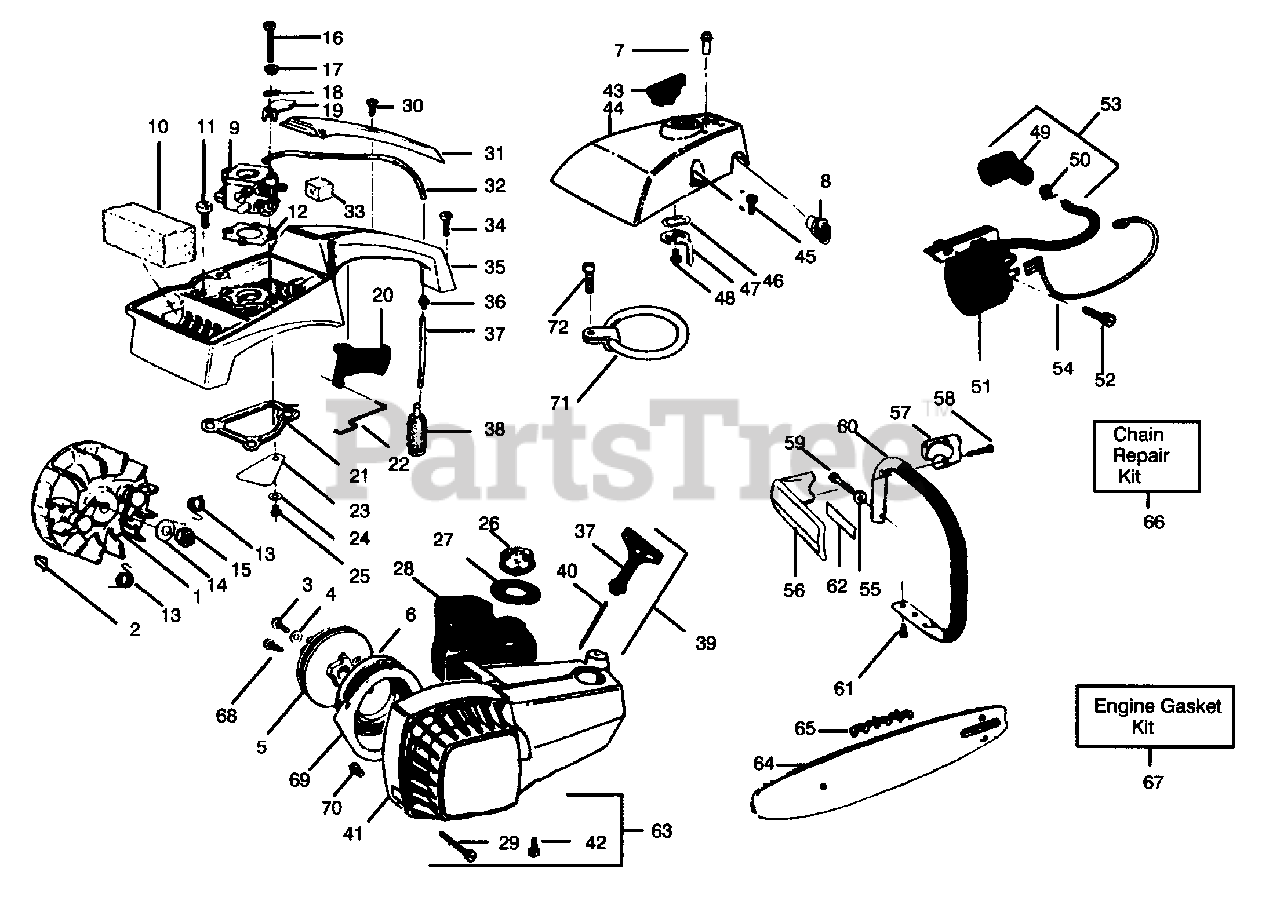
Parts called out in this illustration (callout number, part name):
1	Flywheel Ass'y.
2	Flywheel Key
3	Pulley Retaining Screw
5	Starter Pulley
6	Starter Spring
7	Grommet-Idle-190 only
8	Grommet-Mixture-190 only
9	Carburetor Kit w/Limiter Caps
10	Air Filter
12	Carburetor Gasket
13	Starter Dog Spring
14	Flywheel Washer
18	Wave Washer
19	Choke Shutter
20	Throttle Trigger
21	Gasket
22	Throttle Wire
23	Reed Valve, 190
23	Reed Valve, 180
24	Washer, 190
24	Washer, 180
26	Fuel Cap Ass'y.
28	Fuel Tank Ass'y. (Incl 26, 27 & 38)
29	Screw
31	Handle Cover
32	Line Kit
33	Throttle Wire Boot
35	Handle & Carb. Hsg., 180
35	Handle & Carb. Hsg., 190
36	Fuel Line Fitting
37	Starter Handle-180
38	Fuel Pick-up Ass'y.
39	Ass'y Rope & Handle
40	Rope Kit
41	Fan Hsg. Kit
43	Choke Knob
44	Carb. Cover, 180
44	Carb. Cover, 190
46	Wave Washer
47	Choke Lever
49	Spark Plug Boot
50	Spark Plug Connector
51	Ignition Module Kit
53	Spark Plug Lead
54	Switch Lead
56	Handguard-180
57	Handguard Cap-180
58	Screw-180
60	Handlebar
62	Handguard Decal-180
63	Fan Hsg. Screw Kit
64	Guide Bar, 12"
64	Guide Bar, 14"
64	Guide Bar, 16"
65	Chain, 12"
65	Chain, 14"
65	Chain, 16"
66	Chain Repair Kit
67	Engine Gasket Kit (Incl. 12,21,27 & 33)
68	Rope Retaining Screw
69	Air Baffle-190
70	Screw-190
71	Rope Ring Kit (Incl. 72)
